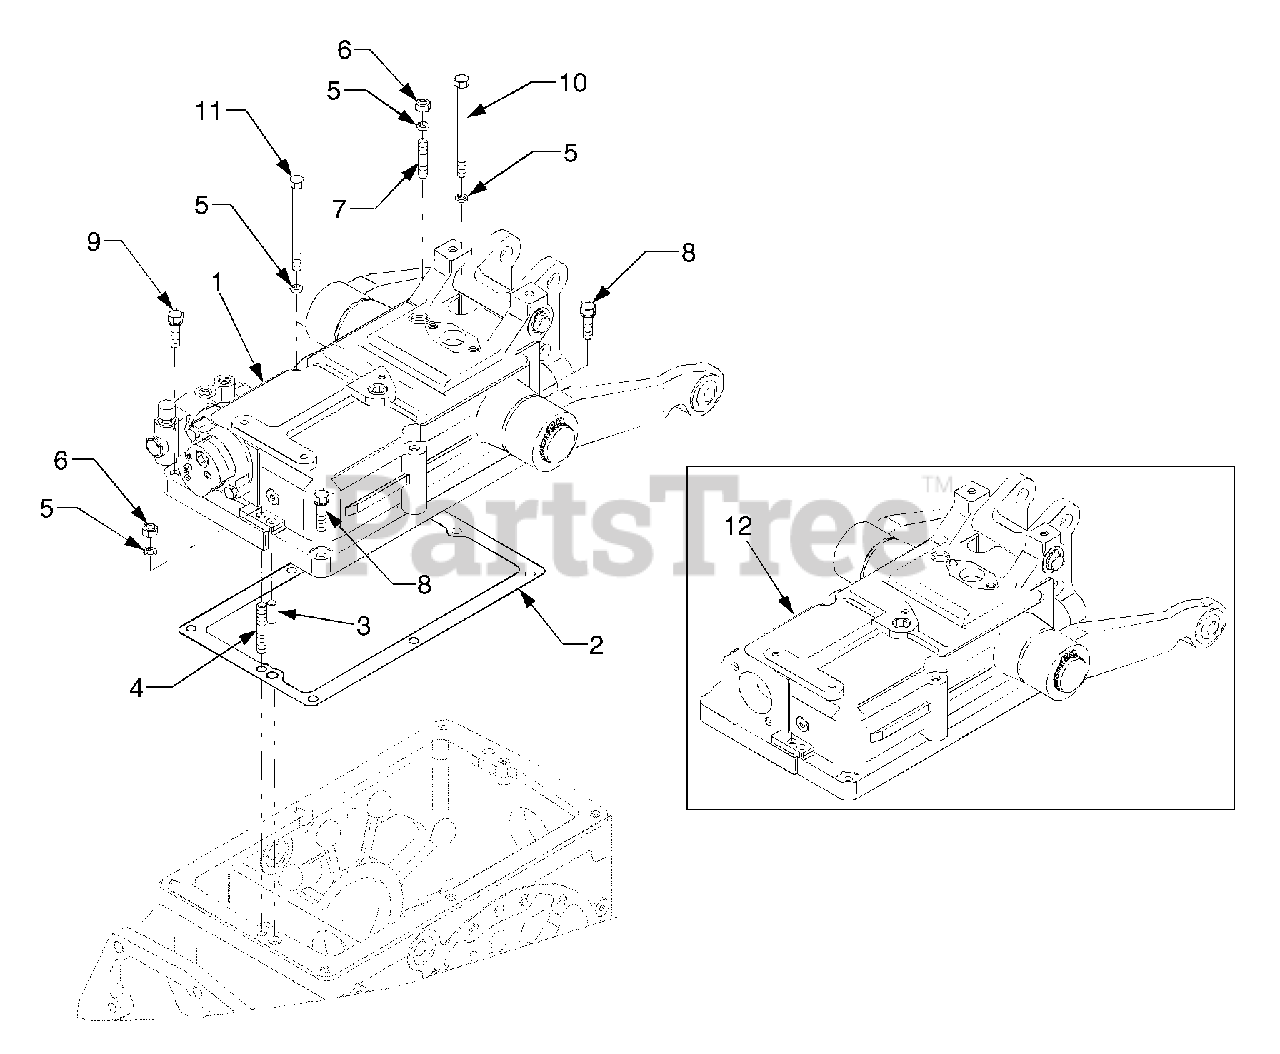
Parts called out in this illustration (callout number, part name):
1	Hydraulic Cylinder Ass'y
3	Pin, Straight
5	Washer, Spring
12	Cylinder, Hydraulic
